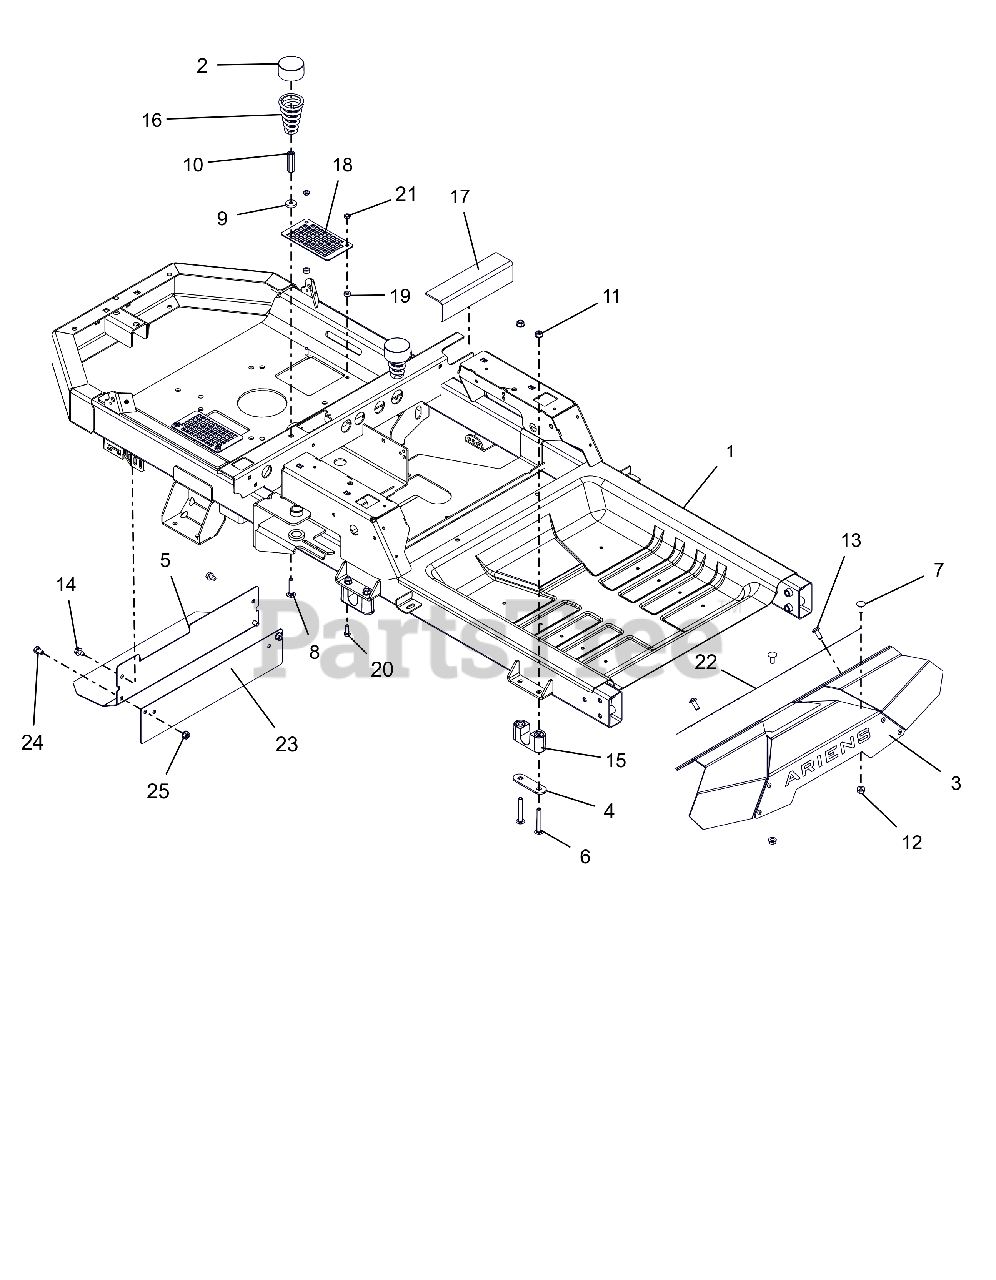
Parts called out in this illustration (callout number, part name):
1	KIT, IKON-X/XL FRAME (2016)
2	HUB CAP
3	KIT, IKON FOOT REST W/DECAL
4	PLATE, BEARING SUPPORT
5	HEAT, SHIELD
6	BLT-RDHDSQSHNK .31-18X2.25 YWZ
7	BLT,RHSN .31-18X.75 G5 ZCC
8	BLT,RHSN .31-18X1.50 G5 ZCC
9	WSHR, FLT .328X.870X.179 ZCC
10	NUT, COUPLING 5/16-18 X 1 3/4
11	NUT,LK-CTR-FLG .31-18 GF ZCC
12	NUT-LK-TOP-FLG .312-18 GF ZCC
13	SCR-RDHDSKTAP .31-18 X .75
14	SCR,TAP .312-18X.50 HWH TR ZCC
15	BSHG, DECK LIFT PIVOT
16	SPRING, SEAT
17	PAD, RUBBER-TANK
18	GUARD, VENT
19	BSHG-SLV .265X.500X.219
20	BLT, HEX .25-20X.75 G5 ZCC
21	NUT-LK-CTR-JAM .250-20 GB ZCC
22	GRIP TAPE, FOOT PLATE
23	GUARD, REAR CLUTCH
24	BLT, HEX .31-18X.50 GR5 ZCC
25	NUT-LK-TOP-FLG .312-18 GF ZCC
